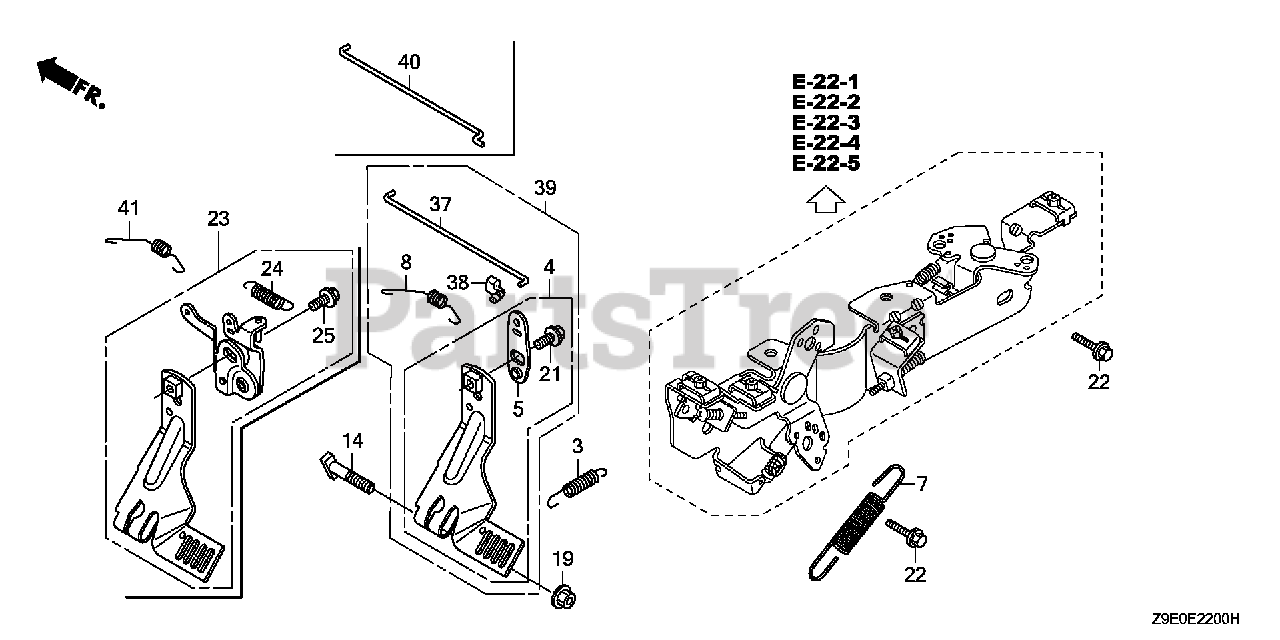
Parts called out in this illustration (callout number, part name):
3	SPRING, STARTER
4	ARM, GOVERNOR
4	ARM, GOVERNOR (NOT AVAILABLE)
5	ARM, SUB
7	SPRING, GOVERNOR
8	SPRING, THROTTLE RETURN
14	BOLT, GOVERNOR ARM
19	NUT, FLANGE (6MM)
21	BOLT, FLANGE (6X10)
22	BOLT, FLANGE (6X14)
37	ROD, GOVERNOR
38	BUSH, LINKAGE
39	ARM KIT, GOVERNOR
